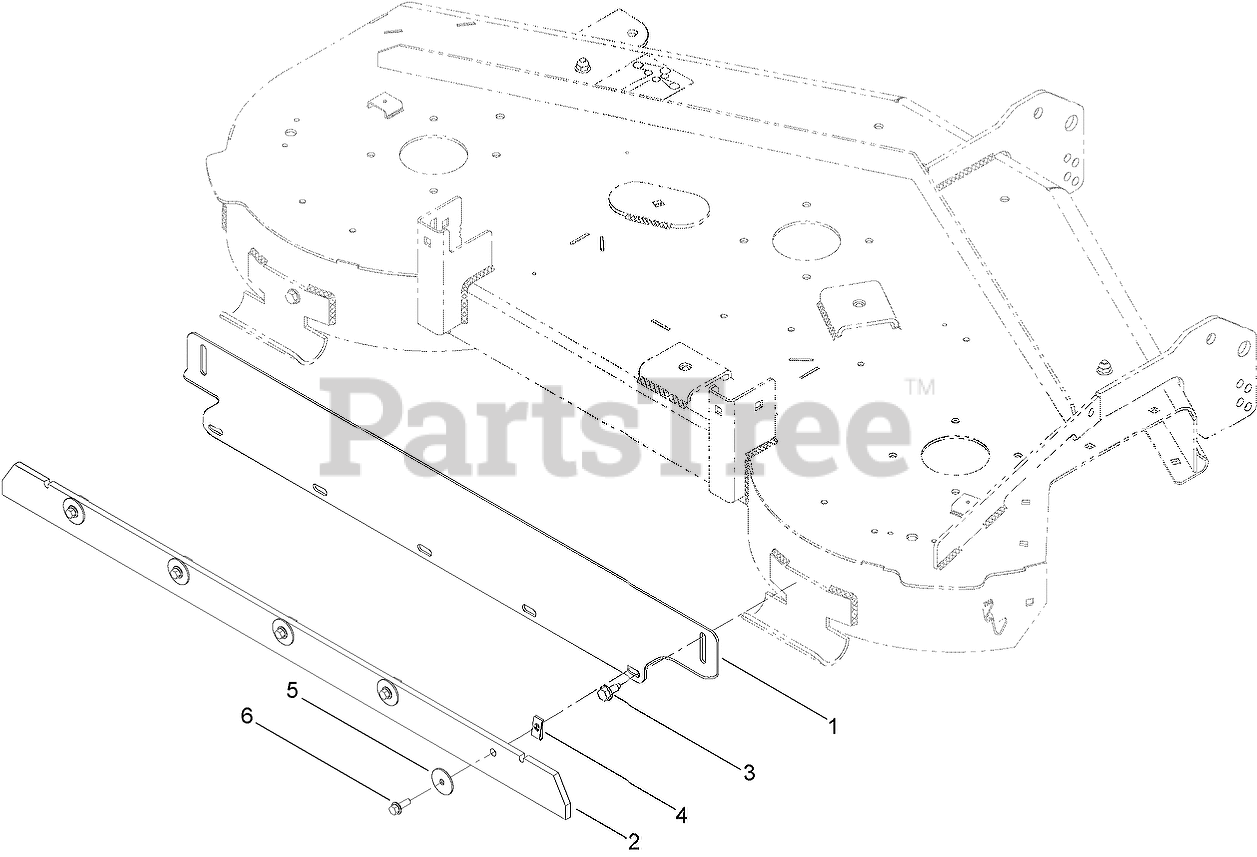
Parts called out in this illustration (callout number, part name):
1	BRACKET-STRIPING, 50IN
3	SCREW-HWHTF
4	NUT-SPEED
5	WASHER-FLAT
6	SCREW-HHF
